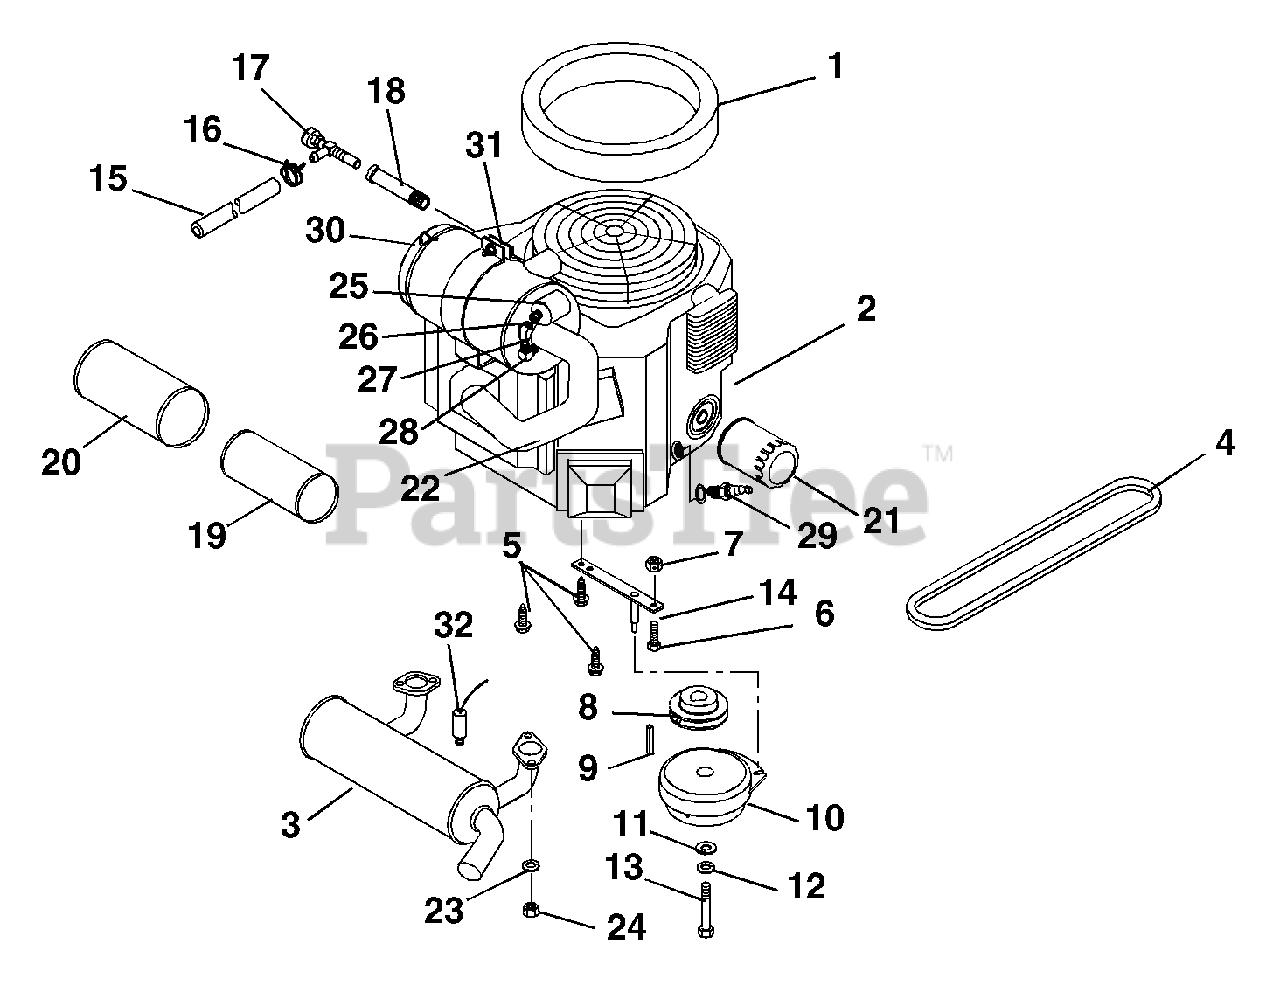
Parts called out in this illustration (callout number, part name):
1	Seal-Foam
2	Engine, Kohler EFI26
3	Muffler, Kohler EFI
4	V-Belt, A-Section 28.29 x .531
5	Screw-Tapping Hex-Washer-Head .38-16 x 1.00
6	Bolt-Hex .31-18 x 1.75 Grade 5
7	Nut-Locking-Center .31-18
8	Pulley-V 4.00 x 1.125 with Key
9	Key-Square .25 x 1.00 x .25
10	Electric Clutch
11	Washer-Flat-Steel .515 x 1.625 x .250
12	Washer-Locking .44 x .109
13	Bolt-Hex .44-20 x 3.00 Grade 5
14	Anchor-Clutch
15	Gas Line-Bulk 1/4" ID
16	Hose-Clamp
17	Cock-Oil Drain
18	Adapter-Oil Drain
19	Element, Inner Safety
20	Element, Outer Primary
21	Oil Filter
22	Hose, Air Intake
23	Washer-Lock .31 x .078 Regular
24	Nut-Hex M8-1.25
25	Filter Minder
26	Nipple, .125" NPT
27	Elbow, 45 Degree 1/8" NPT
28	Elbow,Adapter 90 Degree, Brass, .125 x .125
29	Spark Plug
30	Assembly, Air Cleaner
31	Bracket, Air Cleaner Mount
32	Sensor, Oxygen
